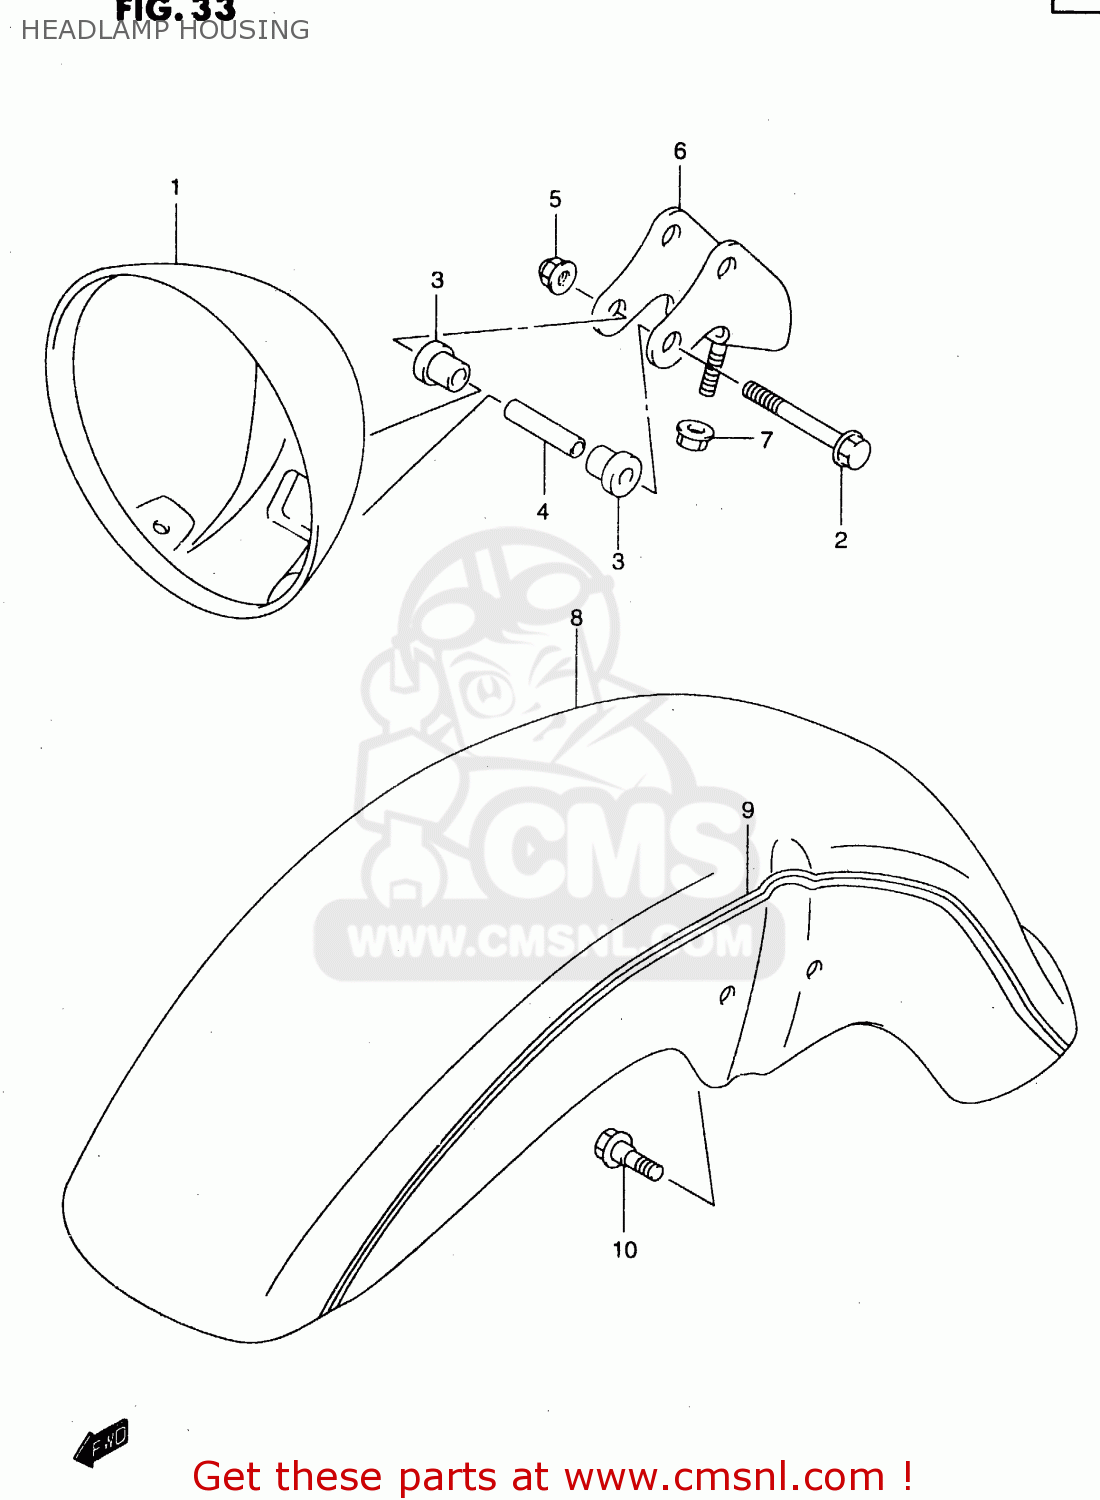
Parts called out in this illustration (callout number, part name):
1	HOUSING,HEADLAMP
2	BOLT
3	CUSHION,HEADLAMP HOUSING
4	SPACER(6.5X9X38.3)
5	NUT
6	BRACKET COMP,HEADLAMP
7	NUT
8	FENDER SET,FRONT (BLACK)
9	TAPE SET,FR FENDER
10	BOLT(6X16)
